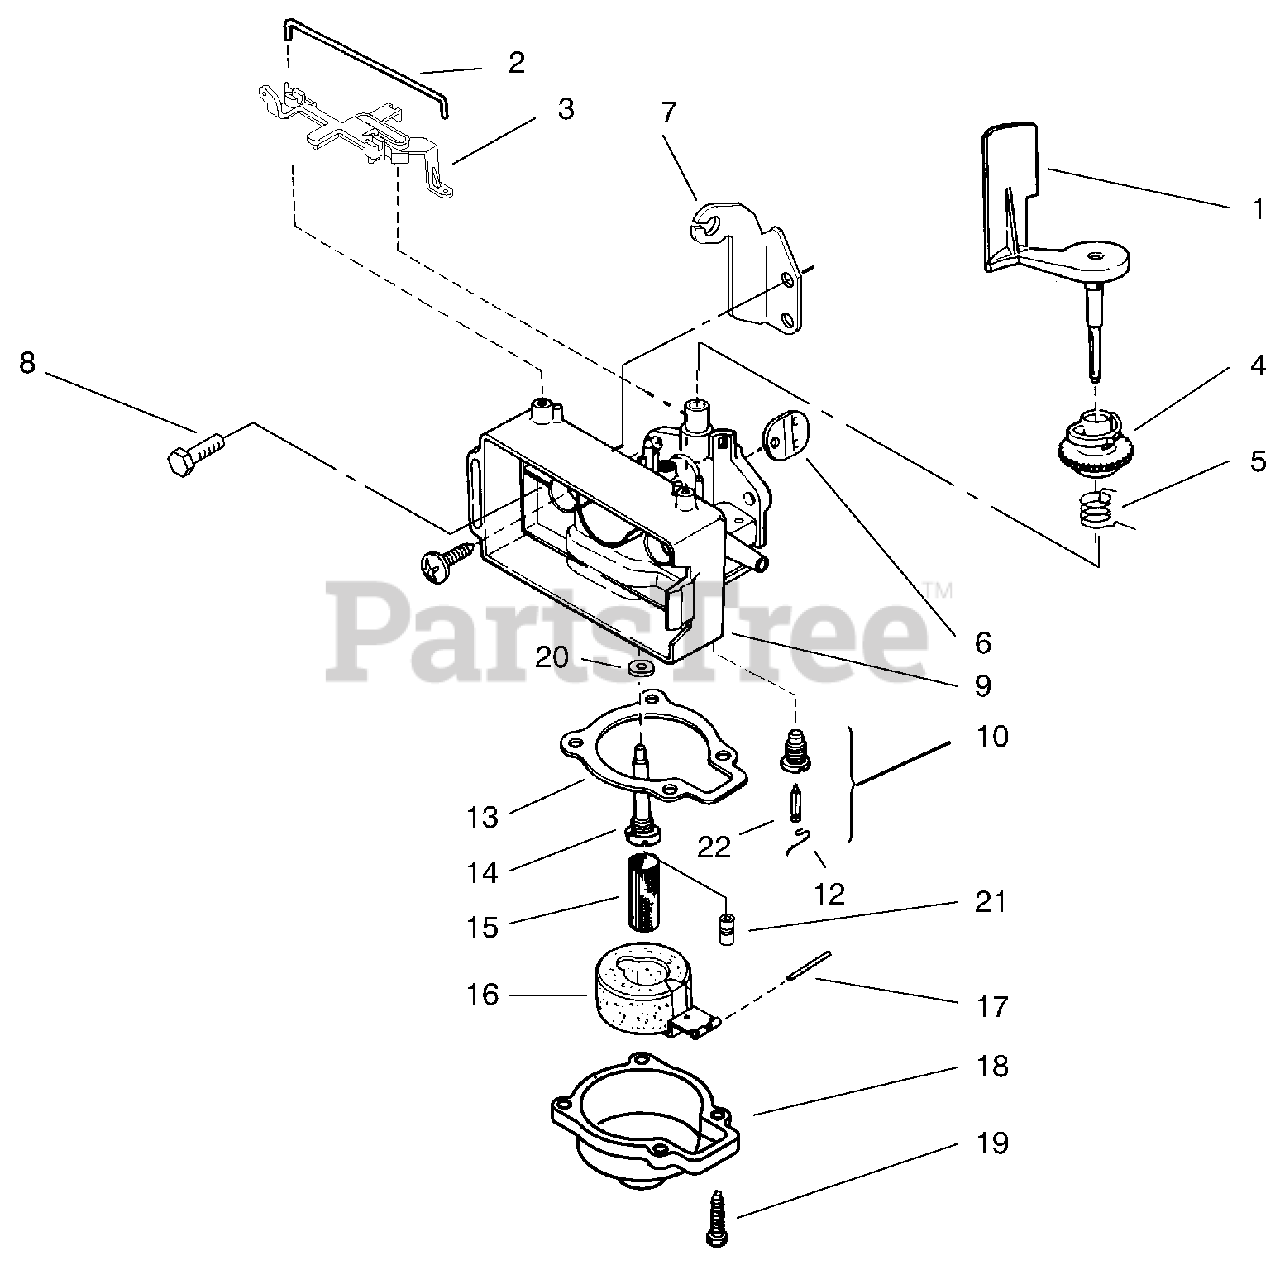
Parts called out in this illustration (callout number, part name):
1	Air Vane & Shaft
2	Retainer-Speed Control
3	Lever-Speed Adjust
4	Collar-Air Vane
5	Spring-Governor
6	Disc-Throttle
7	Bracket-Throttle Control
9	Carburetor Body
10	Kit-Float Valve, Body & Seat (Incl. Ref. #12 & 22)
12	Spring
13	Gasket
15	Filter-Fuel
16	Float & Arm Assembly
18	Float Chamber
21	Main Jet
22	Valve-Float
